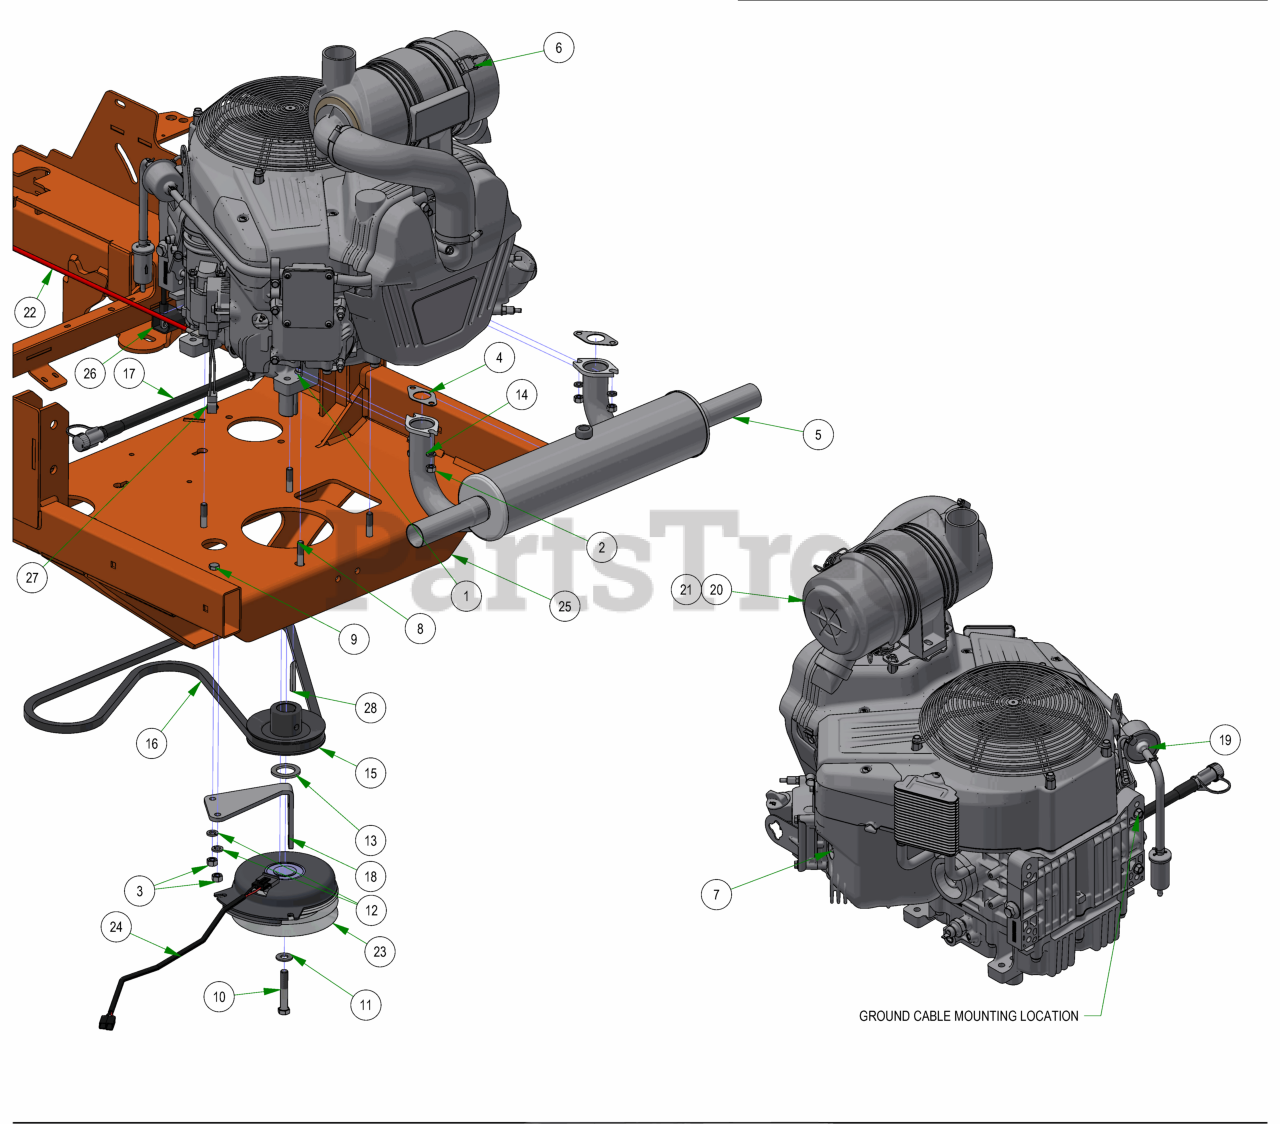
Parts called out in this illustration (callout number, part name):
1	3/8-16 HEX FLANGE TOP LOCKNUT ZINC
2	M8-1.25 DIN 934 HEX NUT (CL.8) ZINC
3	3/8-16 HEX NUT ZINC
4	Exhaust Gasket for 23 Vanguard
5	Muffler for 36Hp Vanguard
6	2019 VANGUARD EFI 37 HP 993cc VERTICAL SHAFT
7	Spark Plug
8	3/8-16x1-3/4 Gr5 Hex Flange Screw Zinc Clear
9	3/8-16 X 1-1/4 HEX CAP SCREW (GR.5) ZINC
10	7/16-20 X 2-1/2 HEX Bolt GR 8 W/ Patch
11	3/8 FLAT WASHER USS (1" OD) ZINC
12	3/8 SPLIT LOCKWASHER ZINC
13	1.140 ID X 1.750 OD X .132 THICK FLAT WASHER PLAIN
14	5/16 SPLIT LOCKWASHER ZINC
15	4 3/4 Motor Pulley
16	2019 Rogue Pump Belt 68"
17	14mm Oid Drain - 36hp Vanguard
18	PTO Engager Holder
19	Universal Inline Fuel Filter
20	Canister Air Filter- Outer
21	Canister Air Filter- Inner
22	24" Red Battery Cable
24	Clutch Pigtail
25	2023 Rogue Frame - Painted
26	Starter Cable
27	2019 Harness Adaptor - Vanguard 37 EFI Vert/Horiz
28	1/4 X 2 SQ MACHINERY KEY 1018 STL PLAIN
